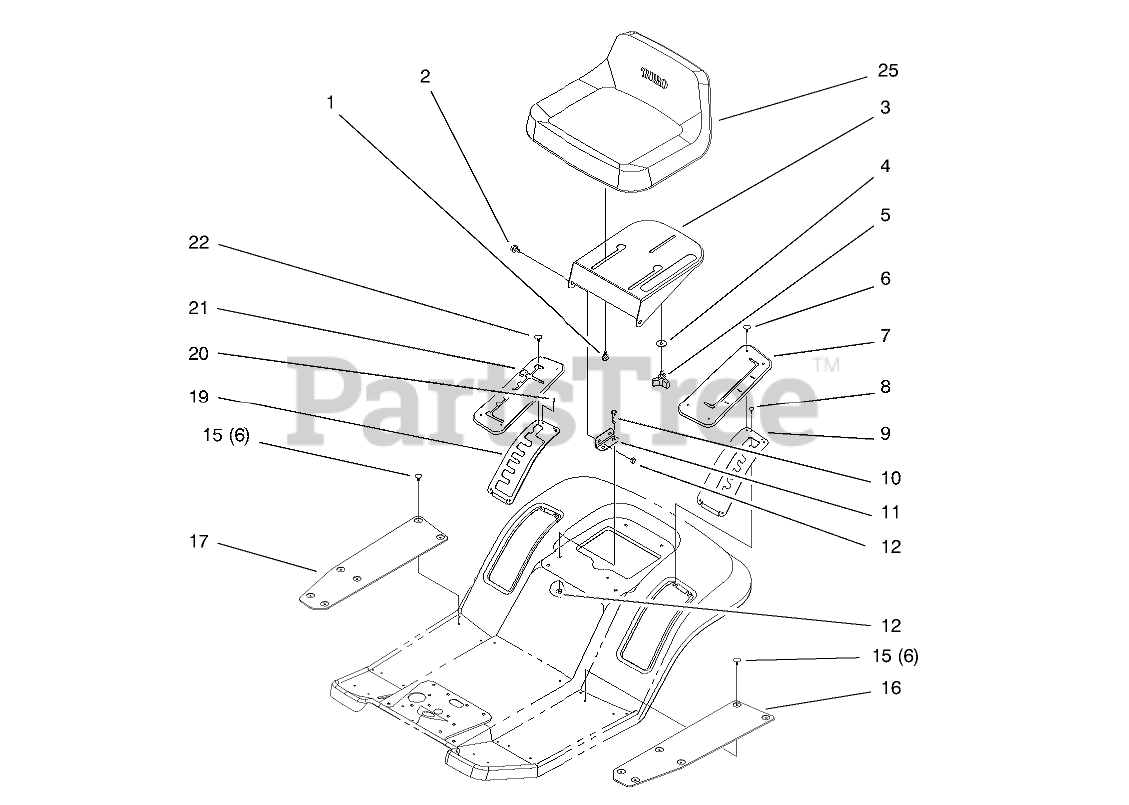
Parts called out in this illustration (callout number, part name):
1	BOLT-SHOULDER
2	BOLT-SHOULDER
3	SEAT SUPPORT (BLACK)
4	WASHER-PIVOT
6	FASTENER-PANEL
7	COVER-HOC
8	RIVET-BLIND
9	GATE-HOC
10	SCREW-HH
11	BRACKET-PIVOT, SEAT
12	NUT-LOCK, NI
15	FASTENER-PANEL
16	MAT-FOOT, LH
17	MAT-FOOT, RH
19	PLATE-GATE, SHIFT
20	RIVET-BLIND
21	COVER-GATE, SHIFT
22	FASTENER-PANEL
25	SEAT
